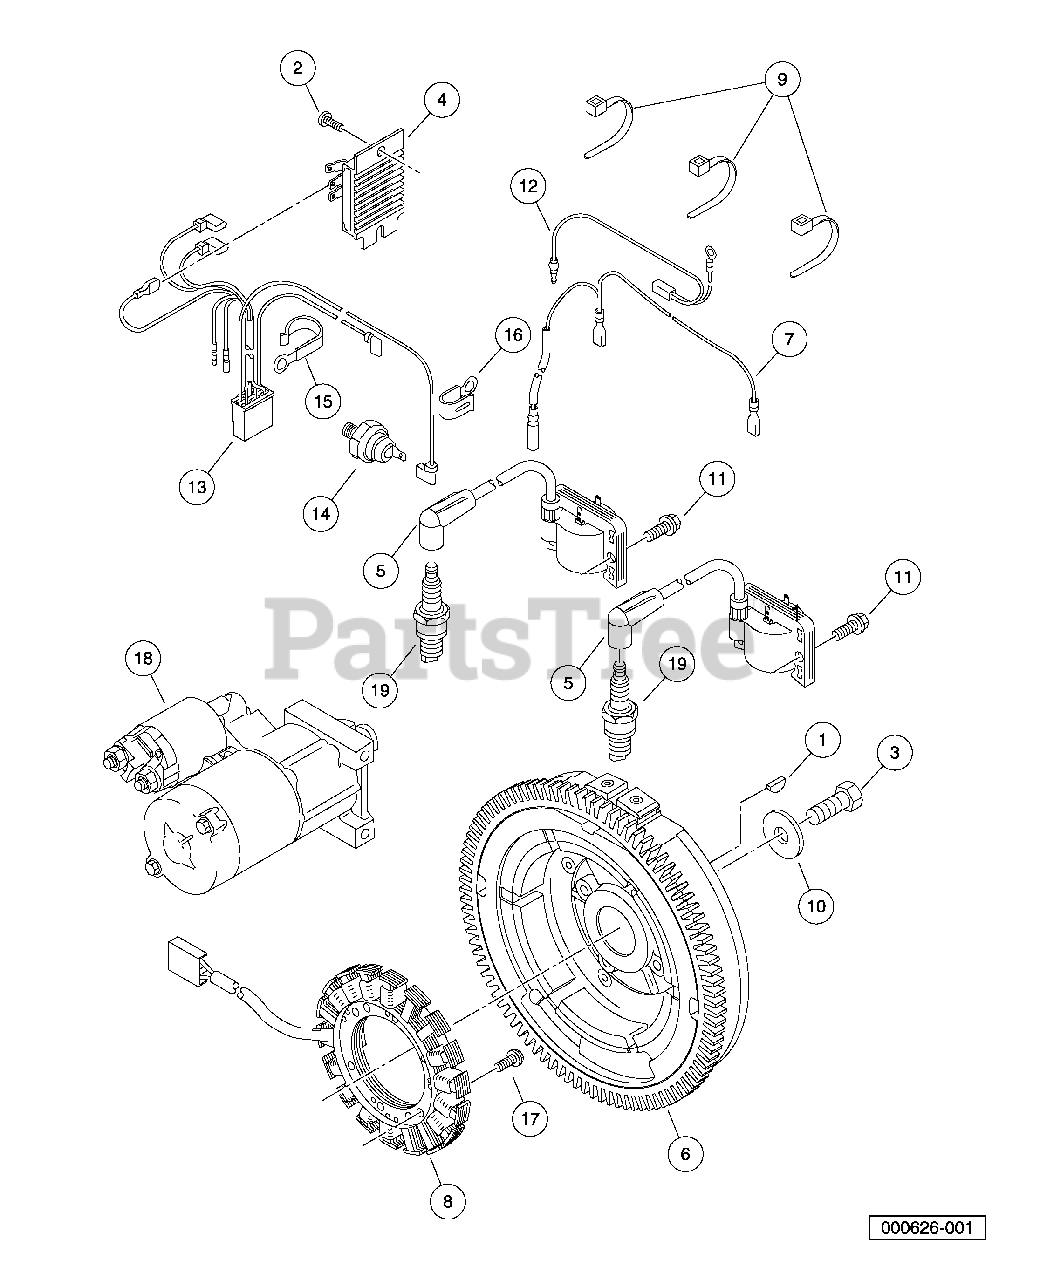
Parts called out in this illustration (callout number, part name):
3	Bolt, Flg, M12 X 1.25 X 30
4	Regulator, Voltage, Fh
5	Coil, Assy, Ignition, Fh
6	Flywheel, Assy, Fh
7	Harness, Regulator, Fh
8	Coil, Charging, Fh
9	Band, Harness, Fh
10	Washer, Flywheel, Fh
11	Bolt, Flanged, M6 X 20, Kaw
12	Harness, Ignition, Fh
13	Harness, Engine, Main, Fh
14	Switch, Oil Pressure, Fh
15	Clamp, Harness, Large, Fh
16	Clamp, Harness, Small, Fh
17	Screw, Pan, Coil Mount, Fh
18	Starter, Electric, Fh680d
19	Spark Plug, BPR2ES
